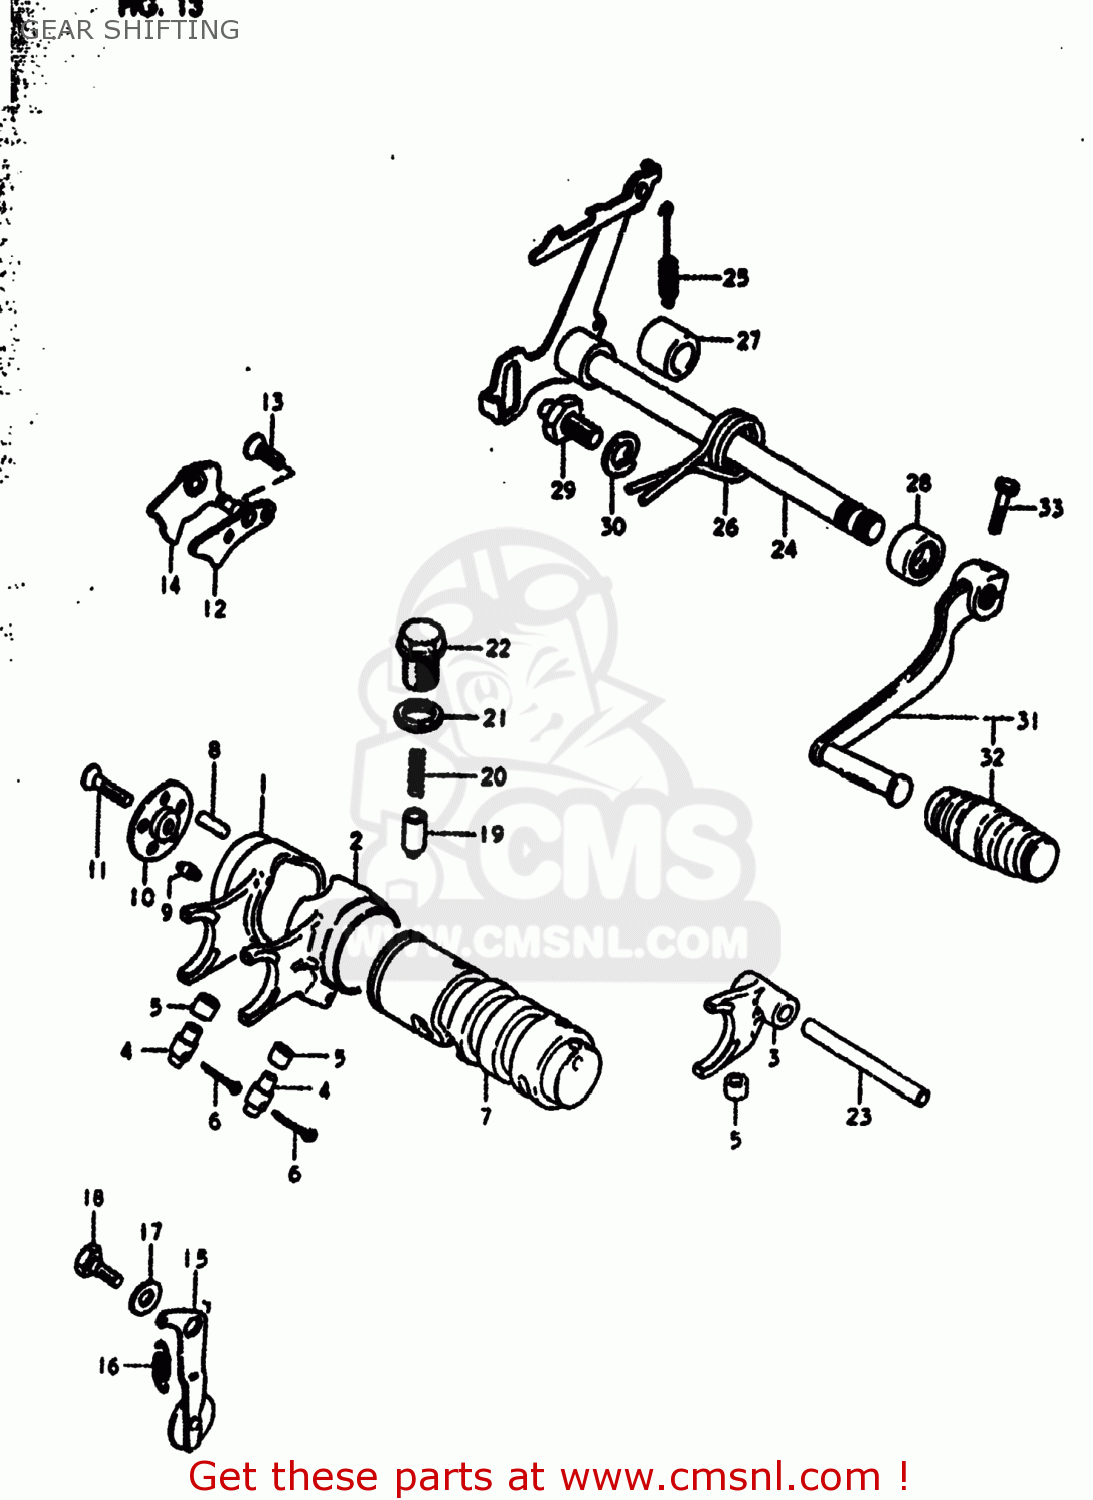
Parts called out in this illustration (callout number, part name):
1	FORK,GEAR SHIFT NO.1
2	FORK,GEAR SHIFT NO.2
3	FORK,GEAR SHIFT NO.3
4	PIN
5	SPACER
6	PIN 25X20
7	CAM,GEAR SHIFT
8	ROLLER(4X13.8)
9	PIN
10	RETAINER,GEAR SHIFT CAM DR PIN
11	SCREW
12	GUIDE,GEAR SHIFT CAM
13	SCREW
14	PAWL,GEAR SHIFT CAM STOPPER
15	STOPPER,GEAR SHIFT CAM
16	SPRING
17	WASHER(6.5X16X2.3)
18	BOLT(6X16.1)
19	STOPPER,GEAR SHIFTING
20	SPRING
21	GASKET(14X19.2X2) (NAS)
22	BOLT,GEAR SHAFT CAM STOPPER
23	SHAFT,GEAR SHIFT FORK
24	SHAFT,GEAR SHIFT
25	SPRING
26	SPRING
27	SPACER(12X20X15.3)
28	OIL SEAL
29	STOPPER,GEAR SHIFT ARM
30	WASHER
31	LEVER ASSY,GEAR SHIFT
32	RUBBER,GEAR SHIFT PEDAL
33	BOLT
